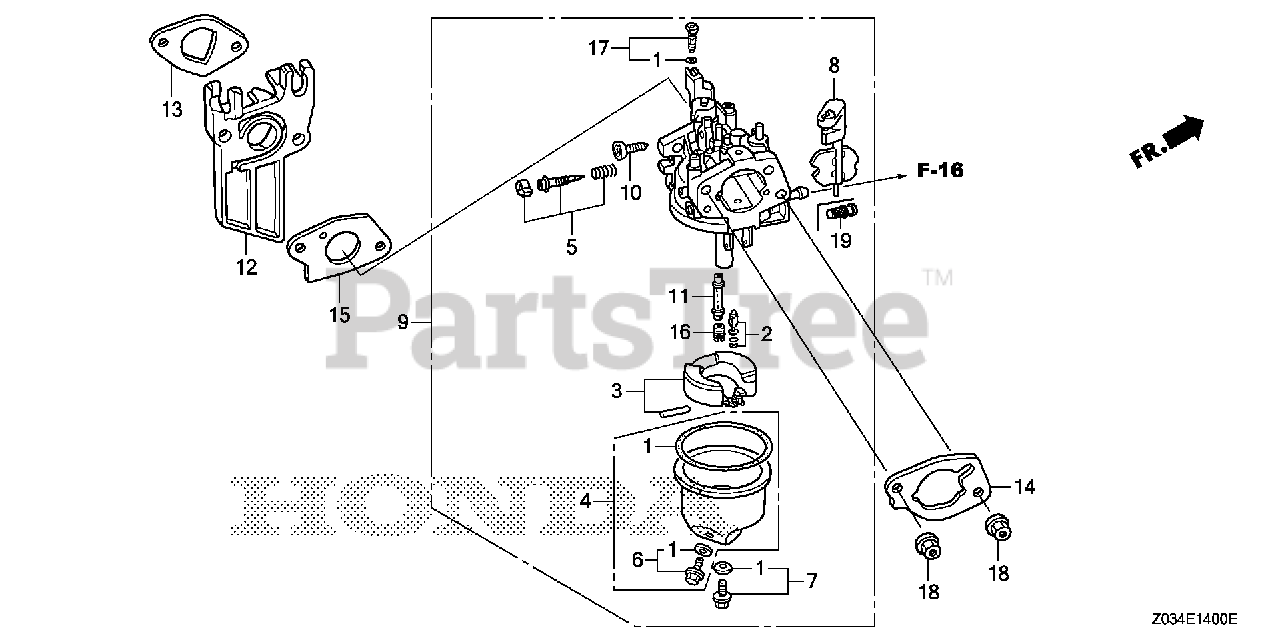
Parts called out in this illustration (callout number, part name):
1	GASKET SET
2	VALVE SET, FLOAT (SEAT NOT INCLUDED)
4	CHAMBER SET, FLOAT
5	SCREW SET, PILOT
6	SCREW SET, DRAIN
7	SCREW SET
9	CARBURETOR ASSY. (BE74E B/C)
10	SCREW, THROTTLE STOP
11	NOZZLE, MAIN
12	INSULATOR, CARBURETOR
13	GASKET, INSULATOR
14	SPACER, CARBURETOR
15	GASKET, CARBURETOR
16	JET, MAIN (#72)
16	JET, MAIN (#70)
16	JET, MAIN (#75)
17	JET SET, PILOT (#45)
18	NUT, FLANGE (6MM)
